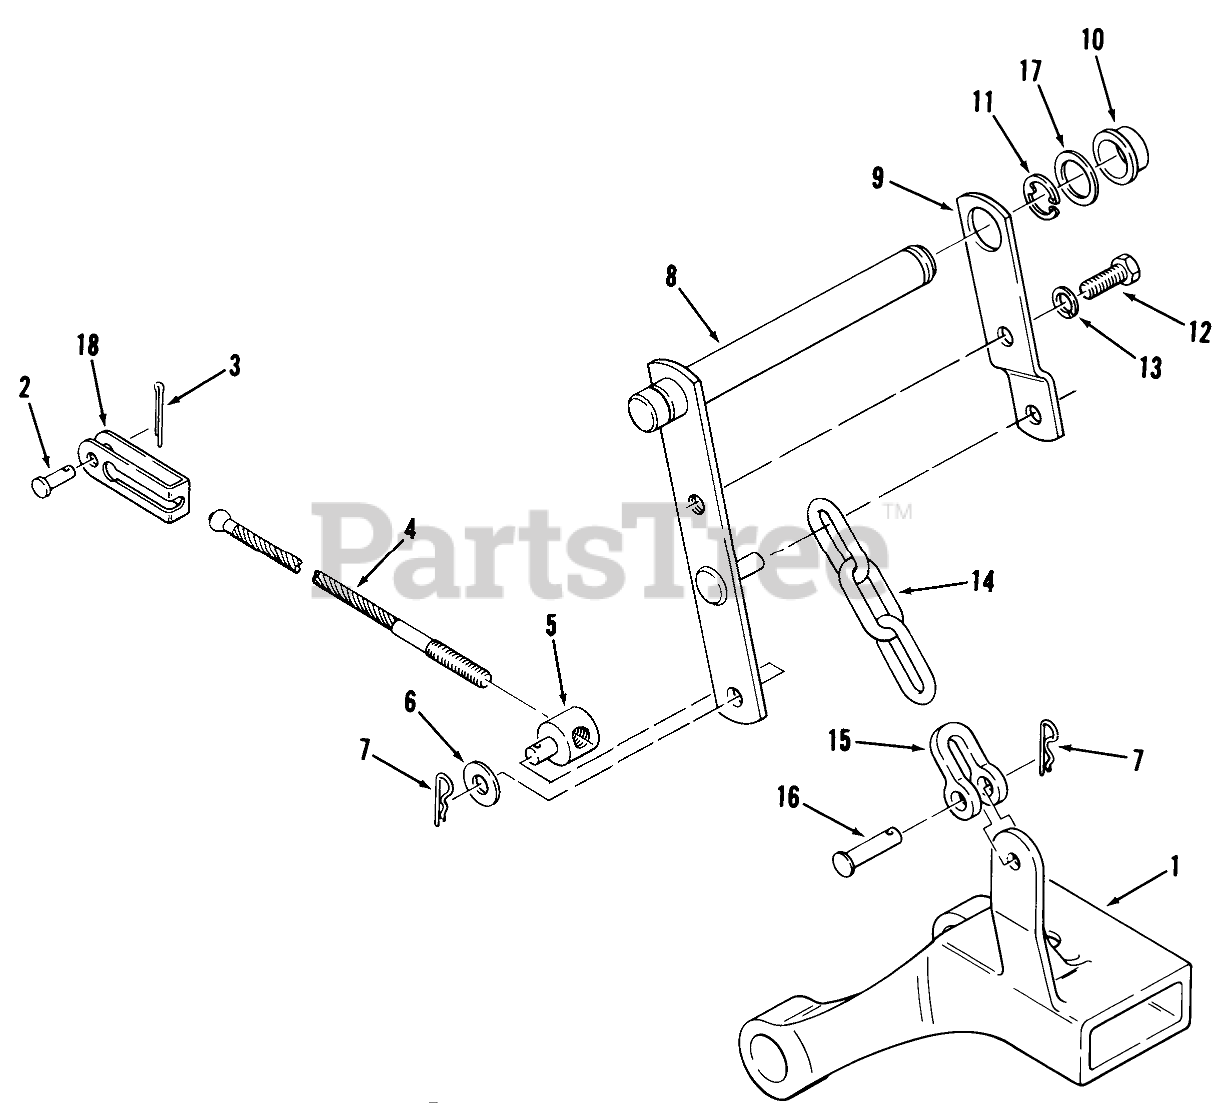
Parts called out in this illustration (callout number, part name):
1	Hitch
2	Pin
3	Cotter Pin
4	CABLE
5	TRUNNION-CLUTCH ROD
6	Washer
7	Hairpin
8	ASSY-LEVER R
9	LOCK BRACKET R
10	BUSHING
11	E-RING
12	Bolt
13	Lockwasher
14	CHAIN-LIFT
15	Clevis
16	Clevis Pin
17	WASHER-SHIM
17	WASHER
18	CLEVIS-SHORT
18	CLEVIS-LONG
